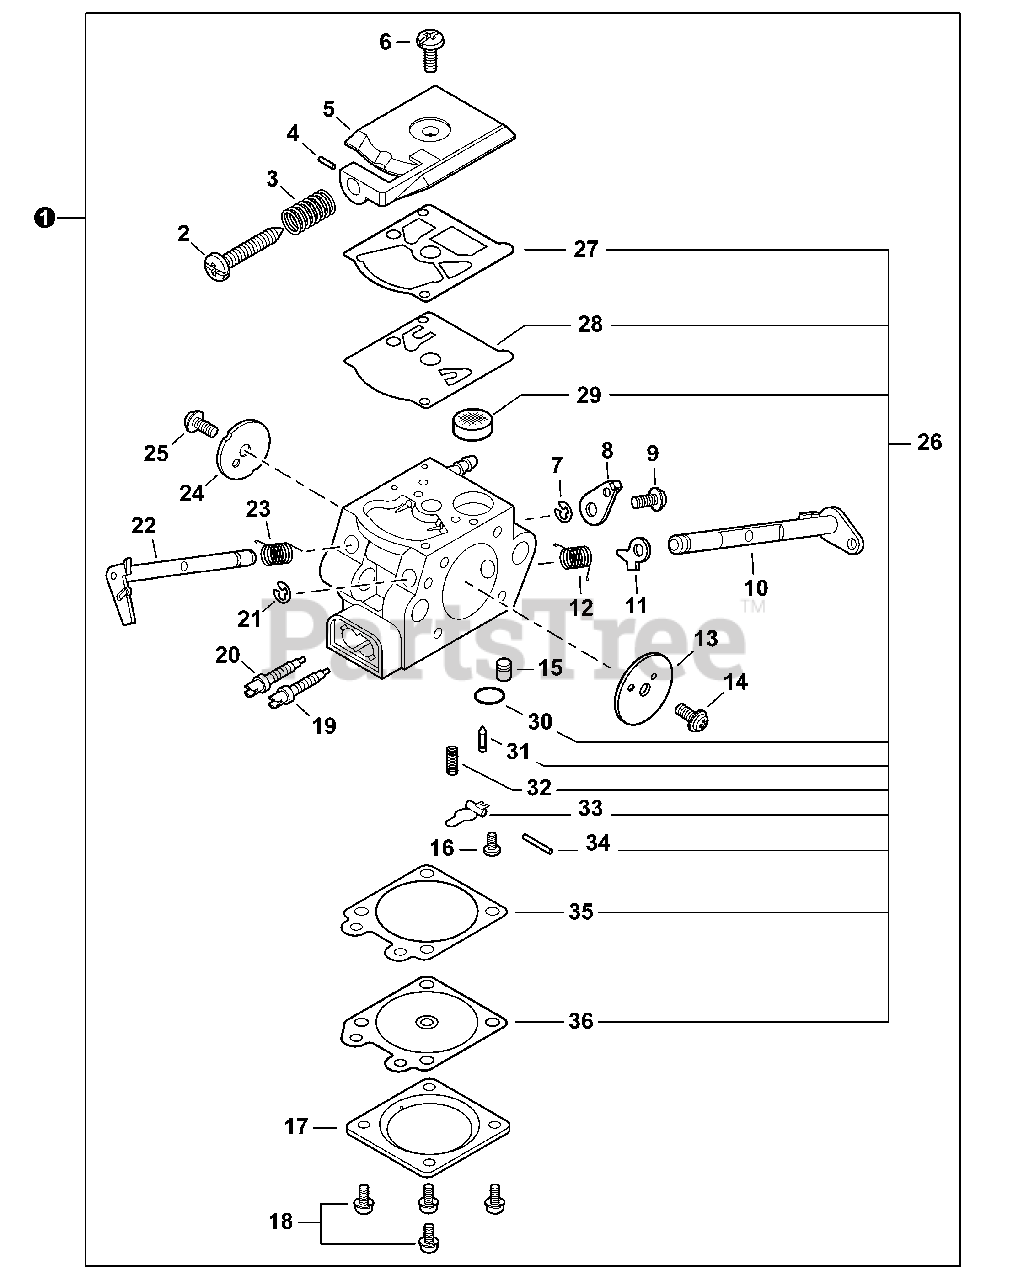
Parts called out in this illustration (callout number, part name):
1	CARBURETOR C1Q-K120A
4	PIECE, FRICTION
5	COVER, PUMP
8	LEVER, THROTTLE
10	SHAFT, CHOKE
11	LEVER, CHOKE
12	SPRING, CHOKE RETURN
13	VALVE, CHOKE
14	SCREW 3×4.5
15	NOZZLE, CHECK VALVE
17	COVER, METERING DIAPHRAGM
19	NEEDLE, HIGH SPEED
20	NEEDLE, IDLE
22	SHAFT, THROTTLE
24	VALVE, THROTTLE
26	REPAIR KIT
27	GASKET, PUMP
28	DIAPHRAGM, PUMP
29	SCREEN, FUEL INLET
30	PLUG, WELCH
31	VALVE, INLET NEEDLE
32	SPRING, COIL
33	LEVER, METERING
34	PIN, METERING LEVER
35	GASKET, METERING DIAPHRAGM
36	DIAPHRAGM, METERING
